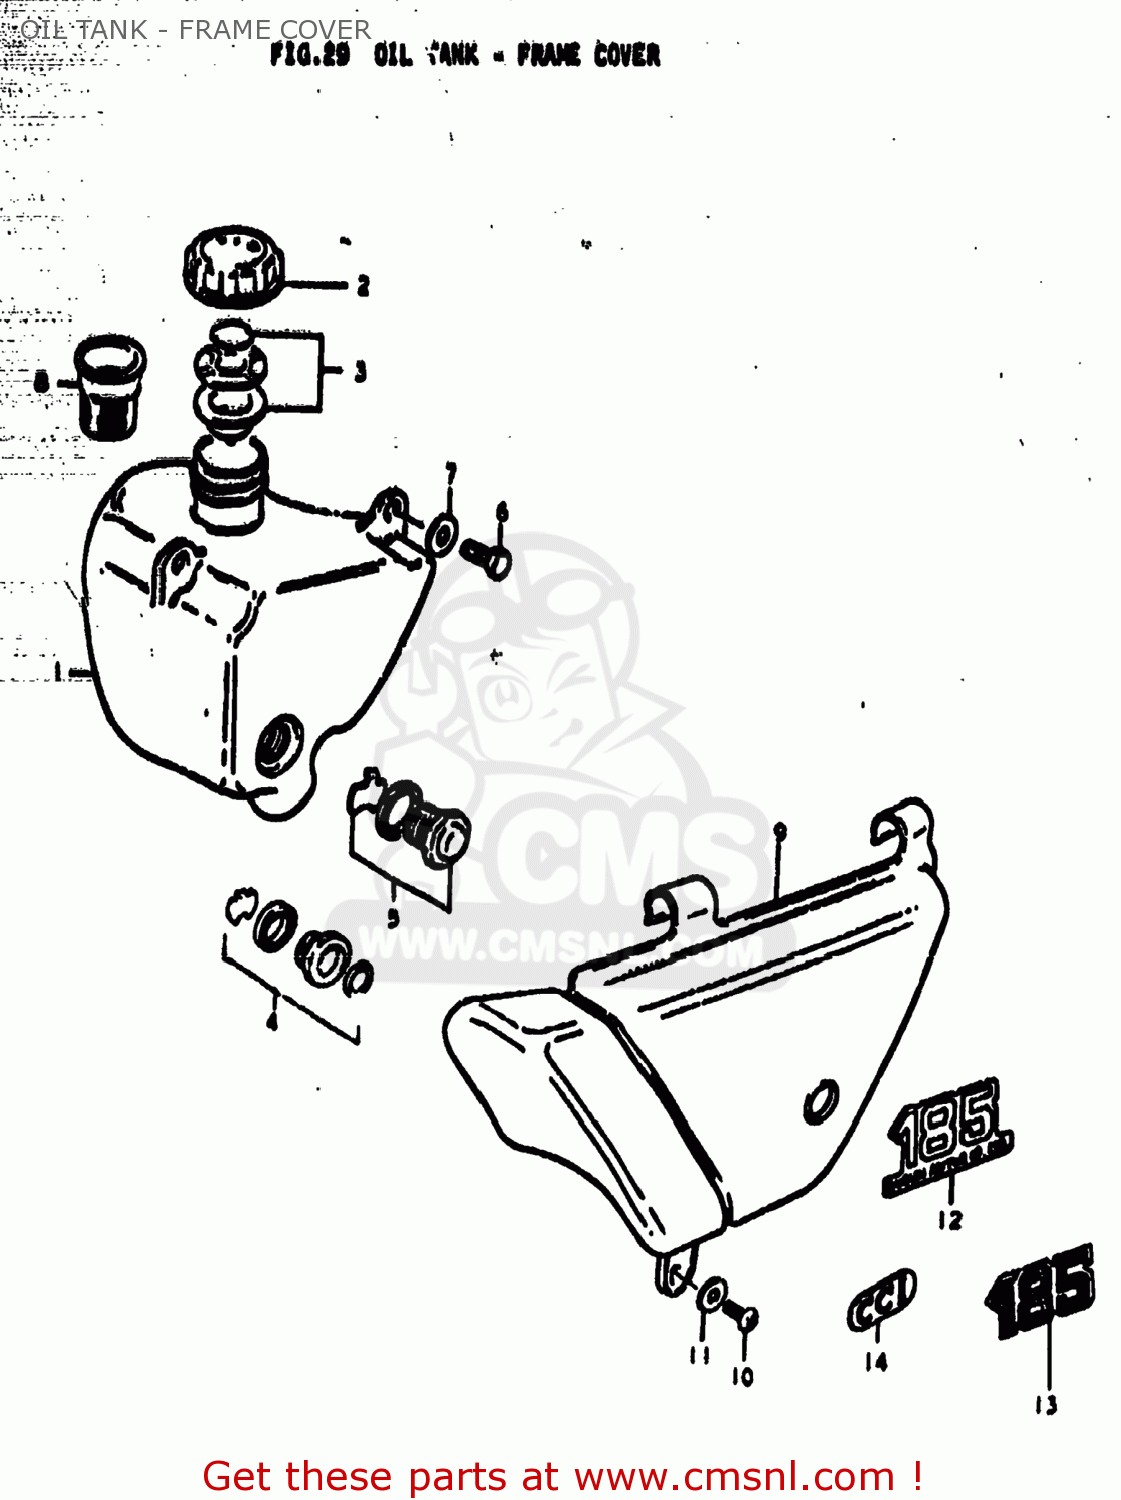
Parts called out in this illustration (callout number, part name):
1	TANK,OIL
2	CAP,OIL TANK
3	GASKET SET
4	LENS SET,OIL LEVEL
5	LENS SET,OIL LEVEL
6	BOLT, UPPER
7	WASHER
8	FILTER,OIL TANK INLET
9	COVER,FRAME,LEFT
10	SCREW 6X12
11	WASHER
12	EMBLEM,FRAME COVER
13	EMBLEM,FRAME COVER
14	EMBLEM,CCIS
